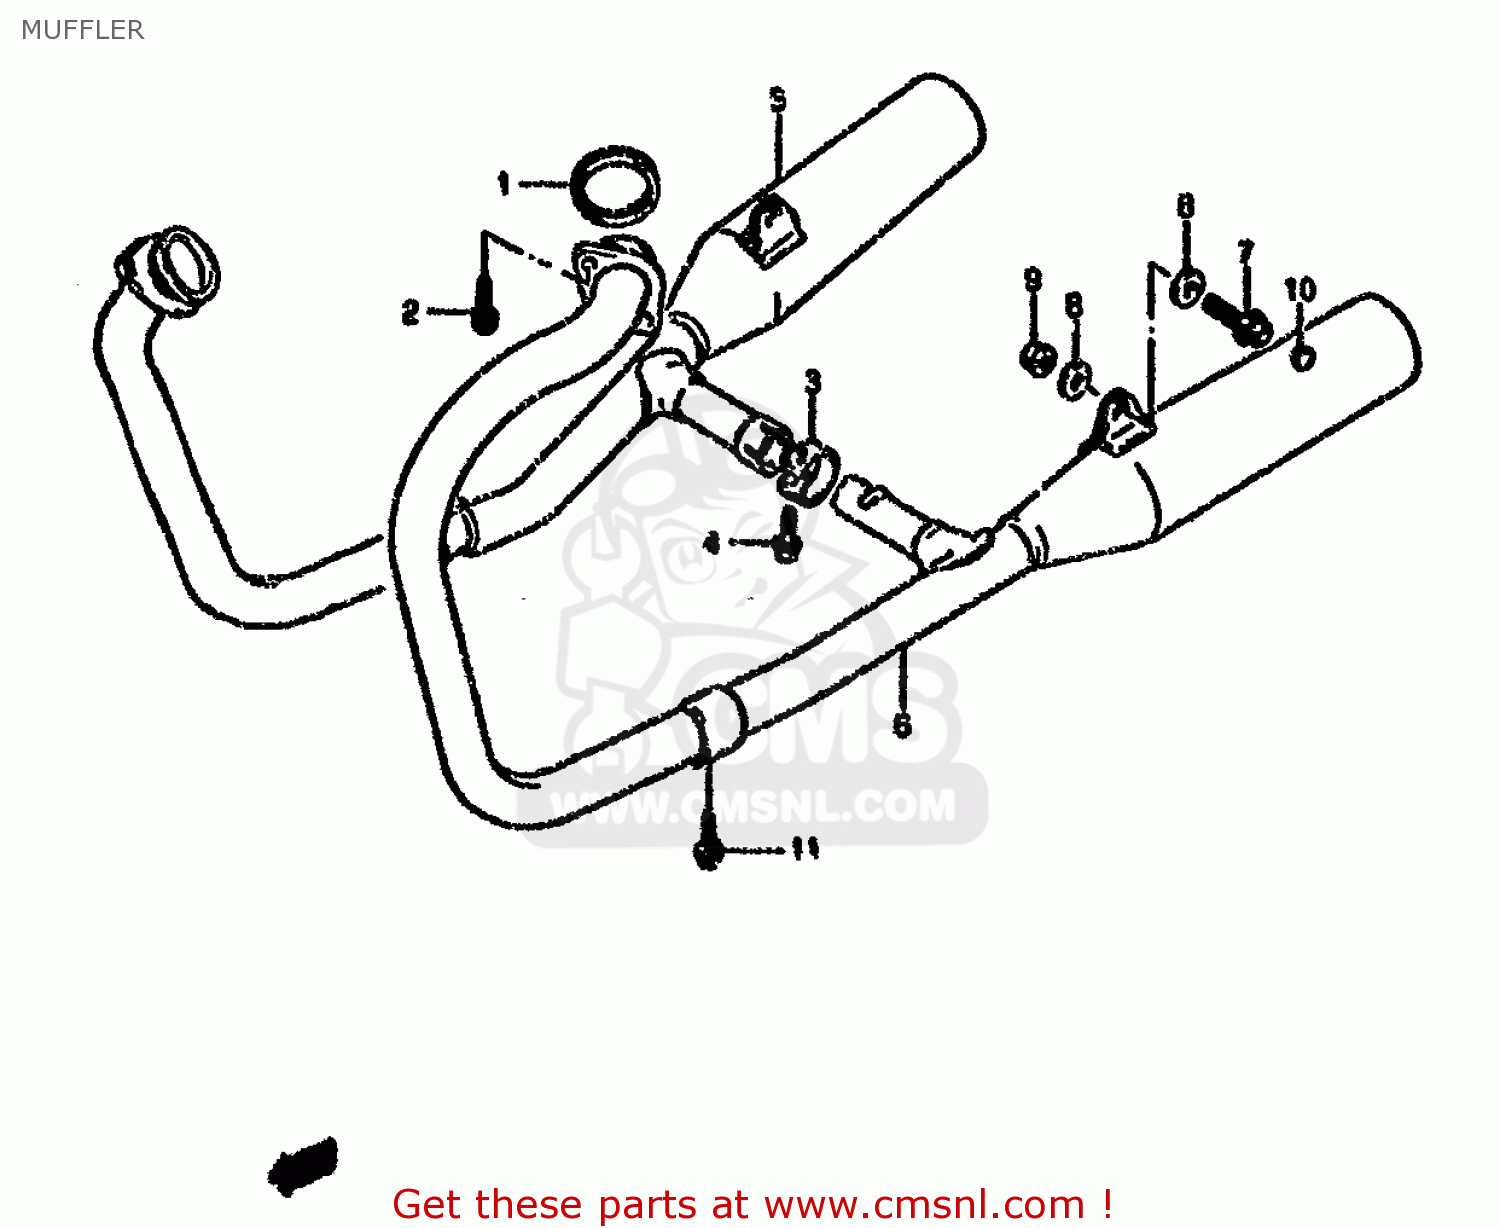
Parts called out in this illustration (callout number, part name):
1	GASKET,EXHAUST PIPE (NAS)
2	BOLT
3	CLAMP,MUFFLER JOINT
4	BOLT
5	MUFFLER,RH
6	MUFFLER,LH
7	BOLT
8	WASHER
9	NUT
10	CAP(OD:12)
11	BOLT
